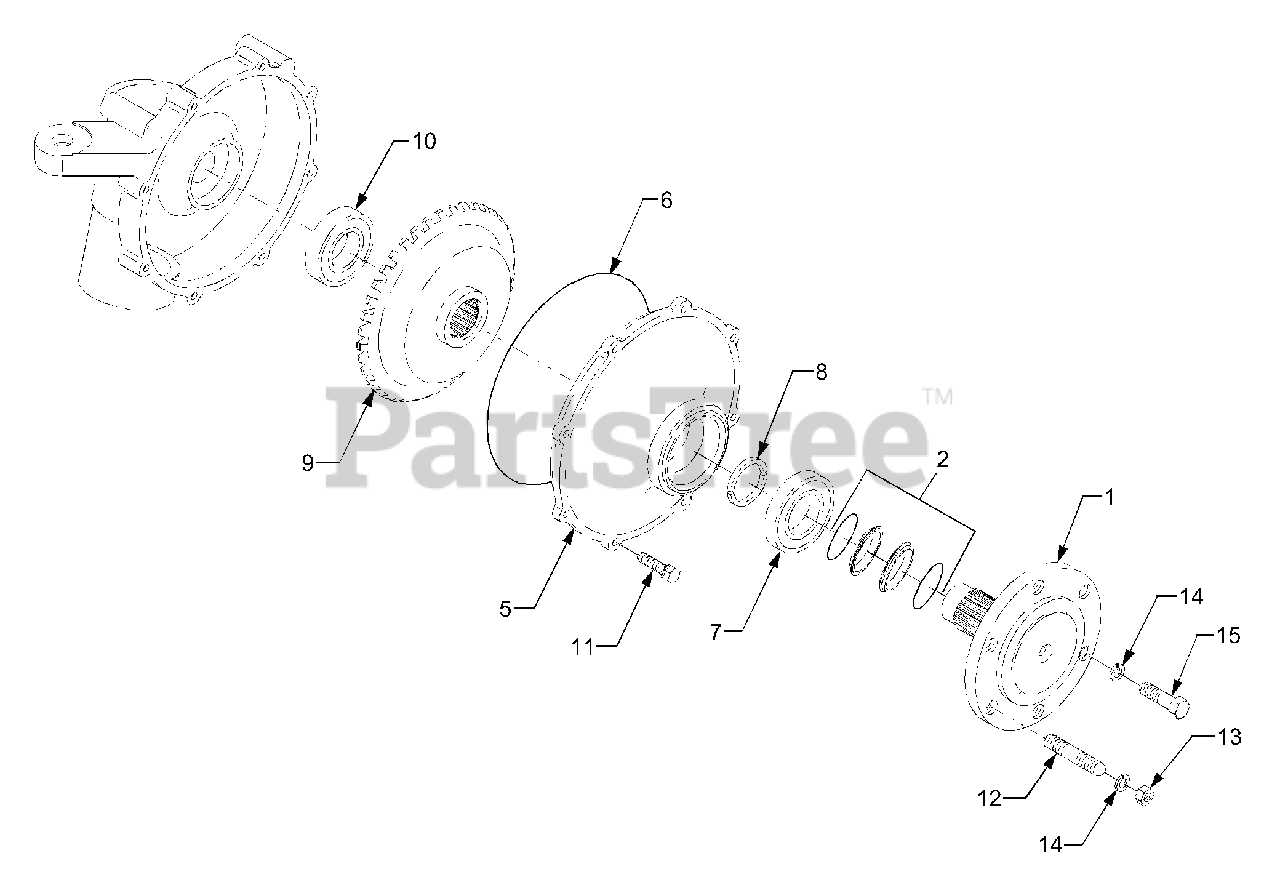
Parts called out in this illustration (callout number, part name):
1	Axle, Front
2	Floating Seal Ass'y
5	Cover, Front Axle
7	Bearing, Ball
9	Gear, 39 Bevel
10	Bearing, Ball
12	Stud
14	Washer, Spring
15	Bolt
